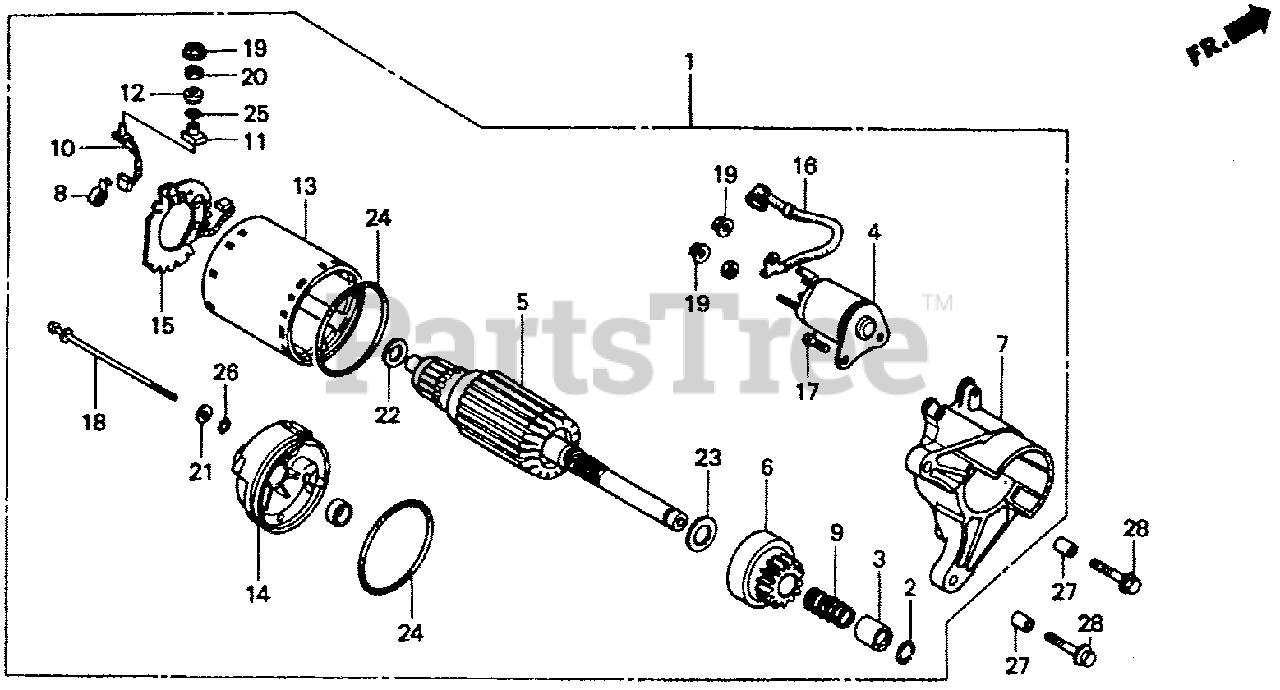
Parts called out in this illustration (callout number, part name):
1	MOTOR ASSY., STARTER
2	RING, SNAP
3	COLLAR, CLUTCH
4	CONTACTOR ASSY.
5	ARMATURE
6	CLUTCH, OVERRUNNING
7	HOUSING, DRIVE SIDE
8	SPRING, BRUSH
9	SPRING
10	BRUSH
11	BUSHING, INSULATION
12	BUSHING, INSULATION
13	YOKE
14	FRAME, STARTER END
15	PLATE, BRUSH HOLDER
16	WIRE, WATER COVER
17	BOLT
18	BOLT, THROUGH
19	NUT
20	NUT
21	WASHER, STEEL PLATE
22	WASHER
23	WASHER
24	O-RING
25	O-RING
26	O-RING
27	PIN A, DOWEL (10X16)
28	BOLT, FLANGE (8X35)
